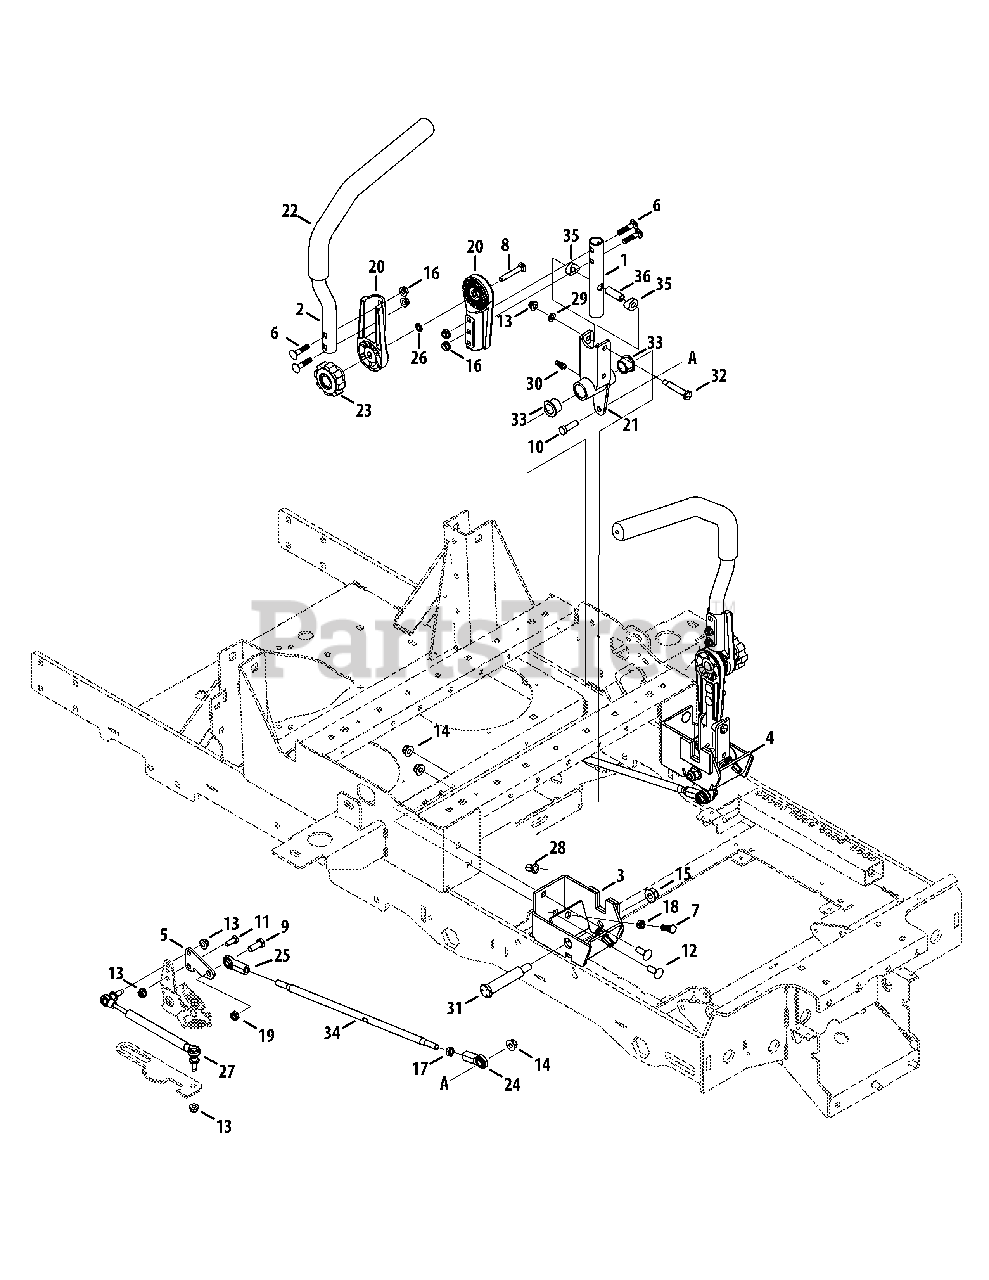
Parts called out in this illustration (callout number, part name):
1	Lower Pivot Tube Weldment
2	Lapbar Tube Weldment
3	Pivot Housing Weldment, RH
4	Pivot Housing Weldment, LH
5	Return to Neutral Control Bracket
6	Carriage Bolt, 5/16-18 x 1.50
7	Hex Cap Screw, 3/8-16 x 1.00
8	Carriage Bolt 5/16-18 x 2.25
9	Hex Cap Screw, 3/8-16 x 1.00
10	Hex Cap Screw, 3/8-16 x 1.25
11	Hex Cap Screw, 5/16-18 x .75
12	Carriage Bolt, 3/8-16 x 1.00
13	Nut, 5/16-18, Flangelock
14	Nut, 3/8-16, Flnagelock
15	Nut, 1/2-13, Flangelock
16	Nut, 5/16-18, Centerlock
17	Jam Nut, 3/8-24
18	Jam Nut, 3/8-16
19	Jam Nut, 3/8-16
20	Handle Adjustment
22	Grip, 1.0 ID
23	Knob, 5/16-18
24	Ball Joint, 3/8-24
25	Ball Joint, 3/8-24, LH
26	Speed Nut, .3125
27	Damper Control Cylinder
28	Rivet Nut, 3/8-16
29	Washer, .330 x .630 x .064
30	Grease Fitting, 1/4-28
31	Shoulder Bolt, .75 x 3.25, 1/2-13
32	Shoulder Screw, .375 x 1.813, 5/16-18
33	Bearing, .75 x 1.00 x .73
34	Control Rod
35	Spacer, .500 x .875 x .250
36	Spacer, .385 x .500 x 1.40
